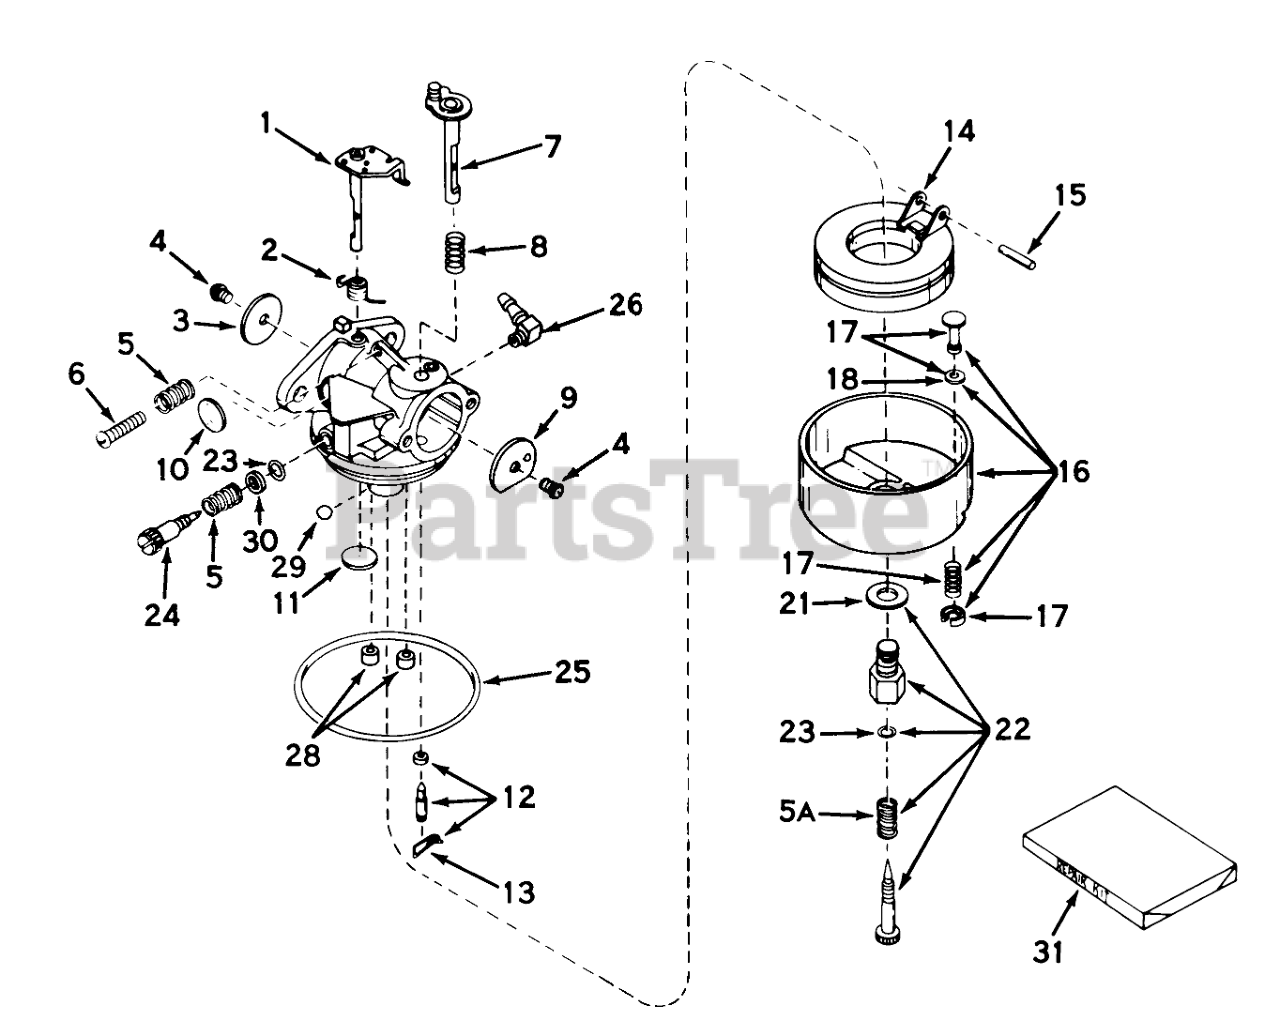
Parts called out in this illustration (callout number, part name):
16	Bowl & Drain Assy., Float (Incl. Nos. 17 & 18)
17	Plunger Assy., Drain (Incl. No. 18)
18	Gasket-Plunger, Drain
21	Washer-Bowl Nut
22	Adjustment Screw Assy., Main (Incl. Nos. 5A, 21 & 23)
23	"O"Ring
24	Screw, Idle Adj.
25	O Ring-Bowl, Float
26	Fitting Fuel Inlet
28	Plug, Cup
29	BalI, Steel
31	Kit-Repair
